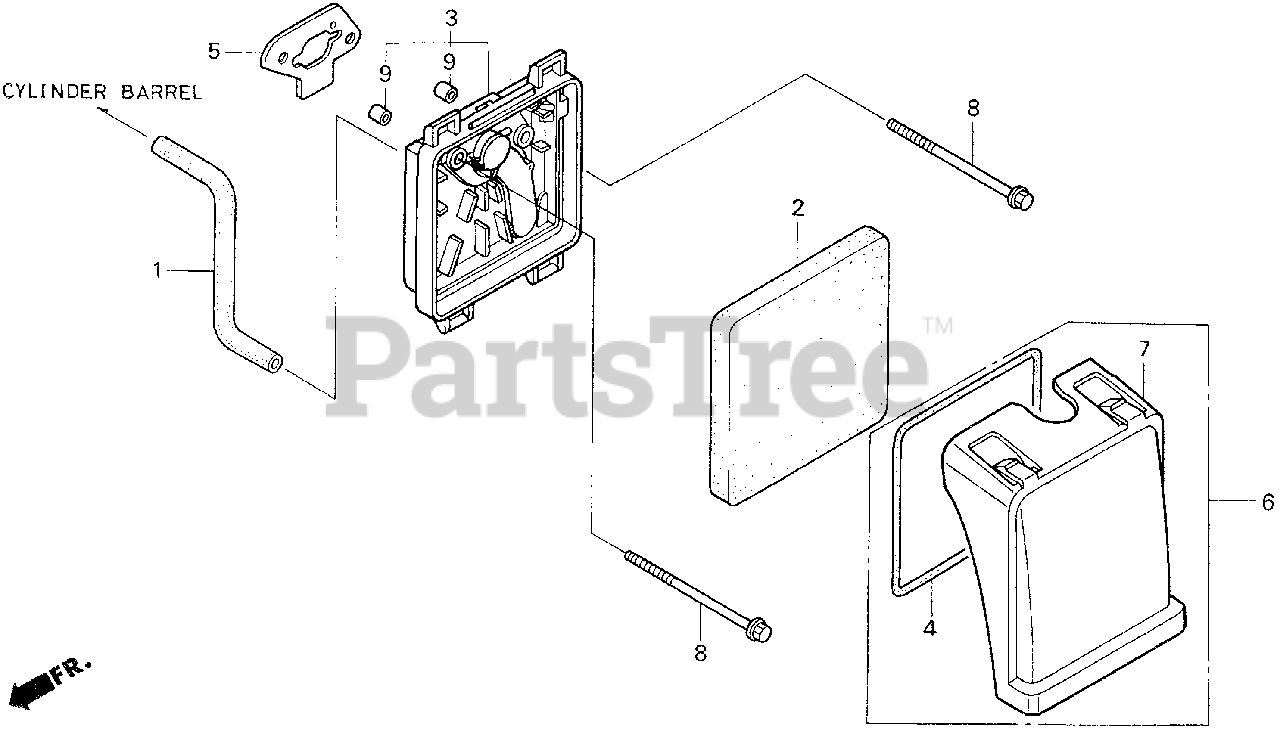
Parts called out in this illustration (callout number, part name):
1	TUBE, BREATHER
2	ELEMENT, AIR CLEANER
3	HOUSING, AIR CLEANER
4	SEAL, AIR CLEANER
5	GASKET, AIR CLEANER
6	COVER, AIR CLEANER
7	COVER, AIR CLEANER
8	BOLT, FLANGE (5X65)
9	COLLAR, AIR CLEANER
